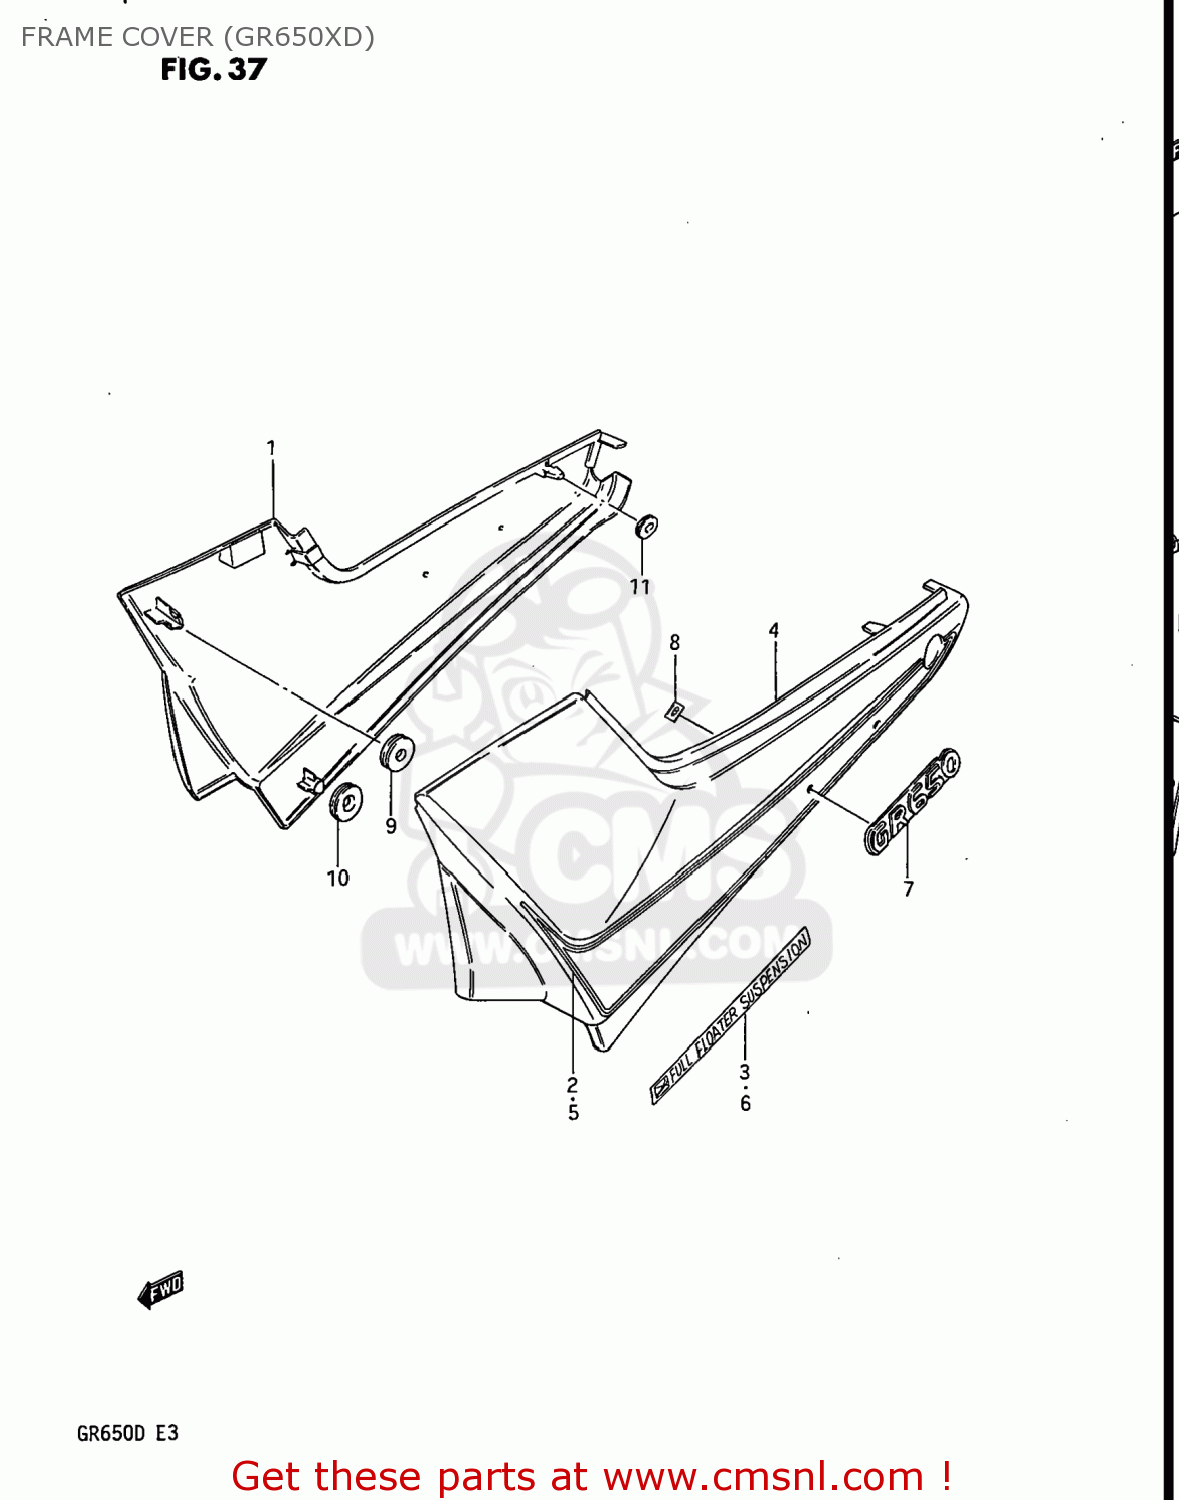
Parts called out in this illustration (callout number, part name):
1	COVER,FRAME,RIGHT
2	TAPE SET,FRAME COVER
3	EMBLEM
4	COVER,FRAME,LEFT
5	TAPE, LH
6	EMBLEM
7	EMBLEM,FRAME COVER
8	NUT
9	CUSHION
10	CUSHION
11	CUSHION
